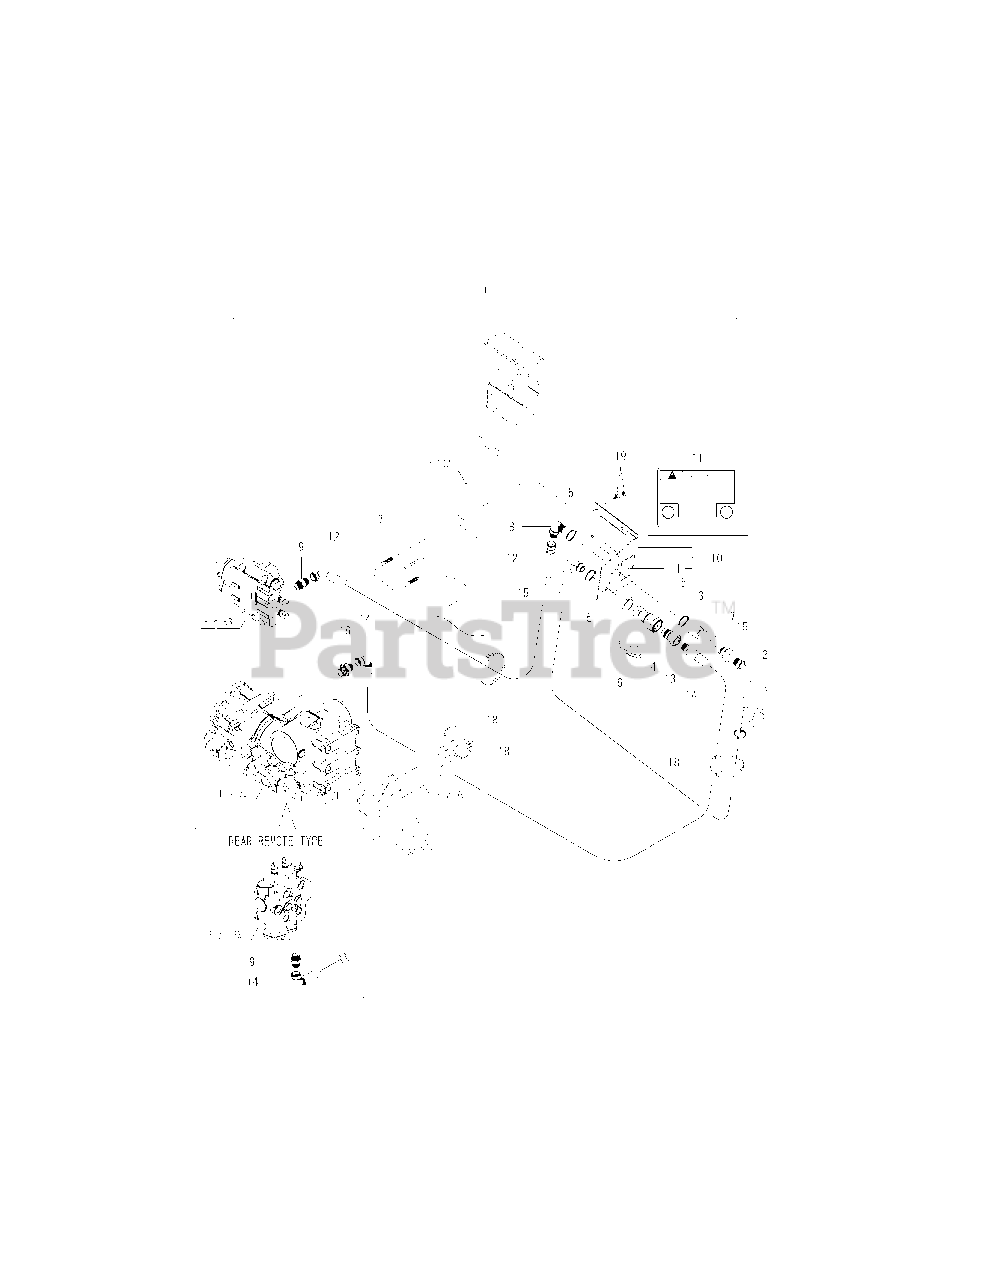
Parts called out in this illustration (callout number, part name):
1	AUX. KIT, REAR HYD.
2	DUST PLUG, M YELLOW
3	COUPLER, QUICK 3/8F
4	COUPLER, QUICK 1/2F
10	BRACKET ASSY, COUPLER
11	LABEL, CAUTION
13	COUPLER, QUICK 1/2M
16	CONNECTOR UNF8-G1/2
17	COUPLER,QUICK 3/8M
